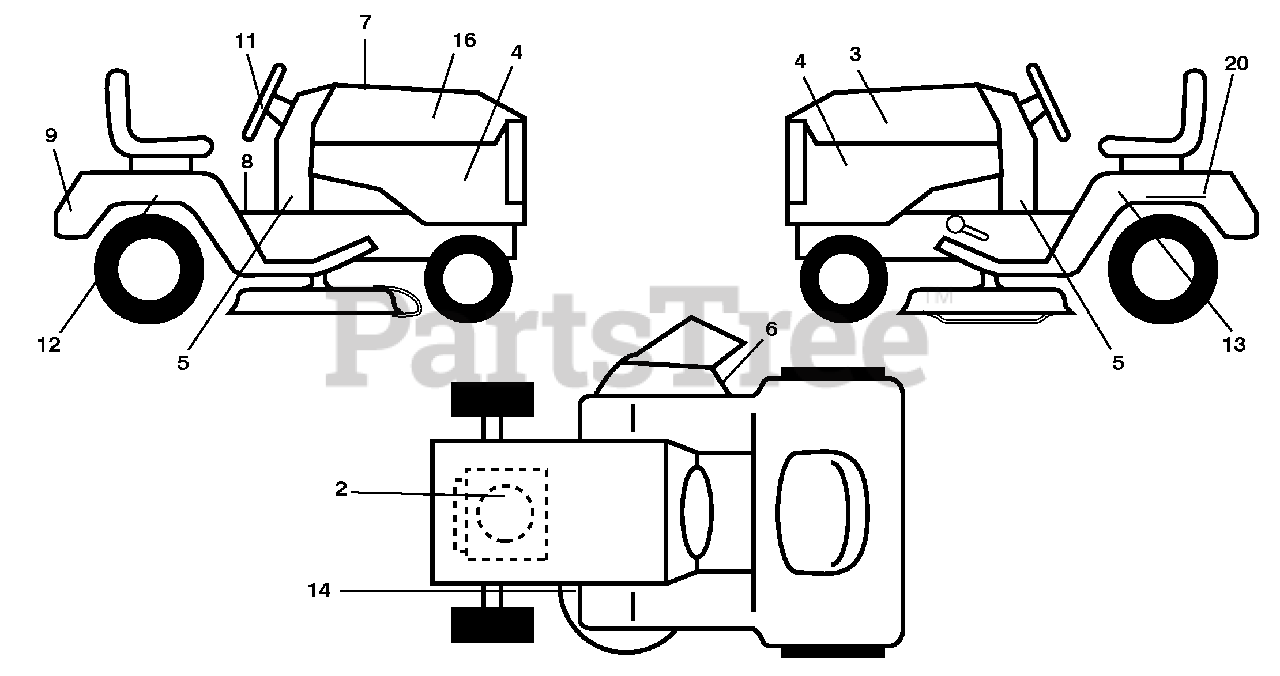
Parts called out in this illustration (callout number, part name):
2	Decal Eng. H.P.
3	Decal Hood LH
4	Decal Side Panel Logo
5	Decal Lwr Dash
6	Decal Warning, Keep Hand Away
7	Decal Replacement Parts
8	Decal Fender Warn S/F
9	Decal Fender Logo
11	Decal Ins Strg Whl
12	Decal Fend SD RH
13	Decal Fend SD LH
14	Decal V-Belt Schematic
16	Decal Hood RH
20	Decal Bat Dan/Psn
20	Pad Footrest LH
20	Pad Footrest RH
20	Manual Operator's (Eng/French)
20	Manual Parts (Eng/French)
